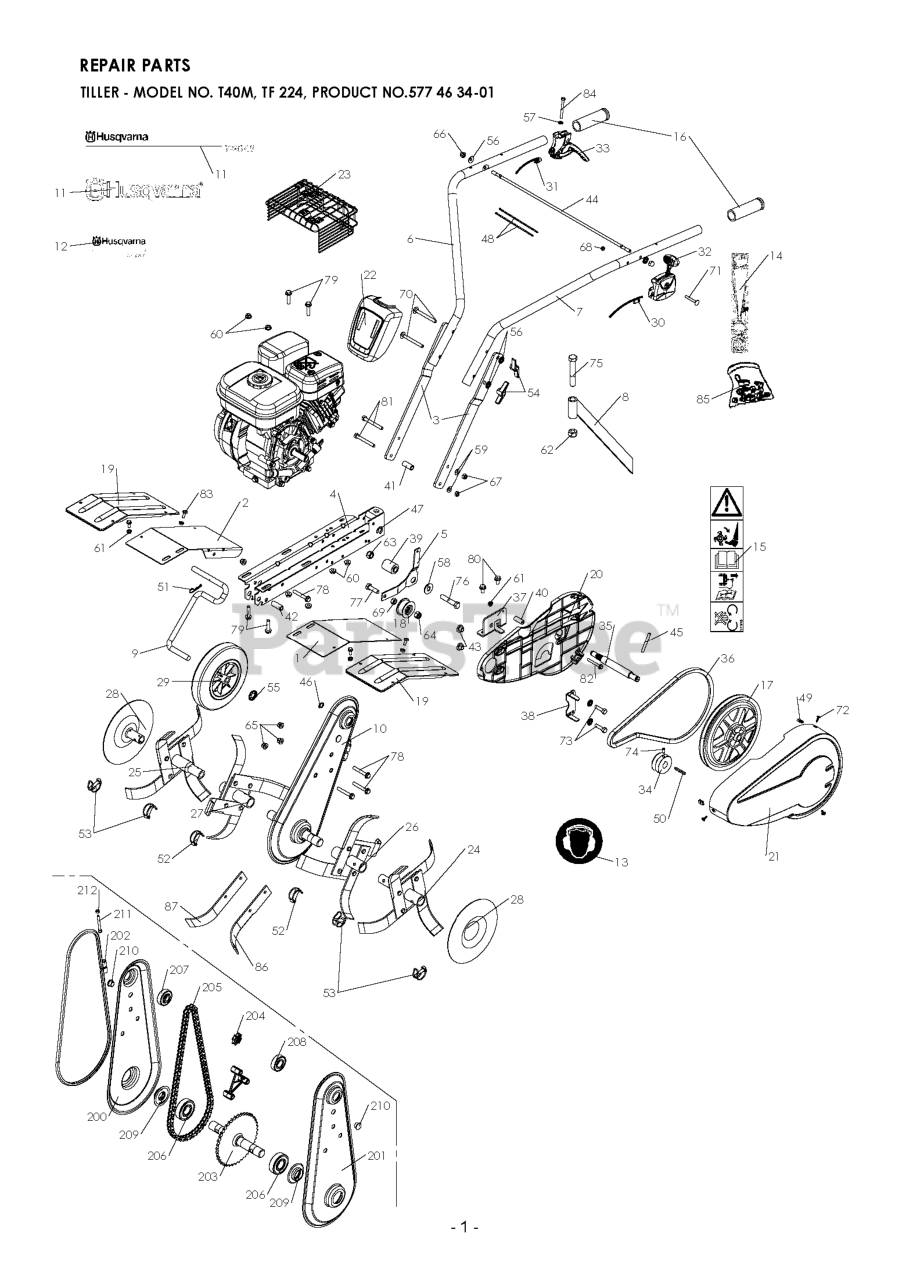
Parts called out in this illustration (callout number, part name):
47	RETAINER RING
51	COTTER PIN
68	Blocking nut M 6 Z
212	Blocking nut M 6 Z
